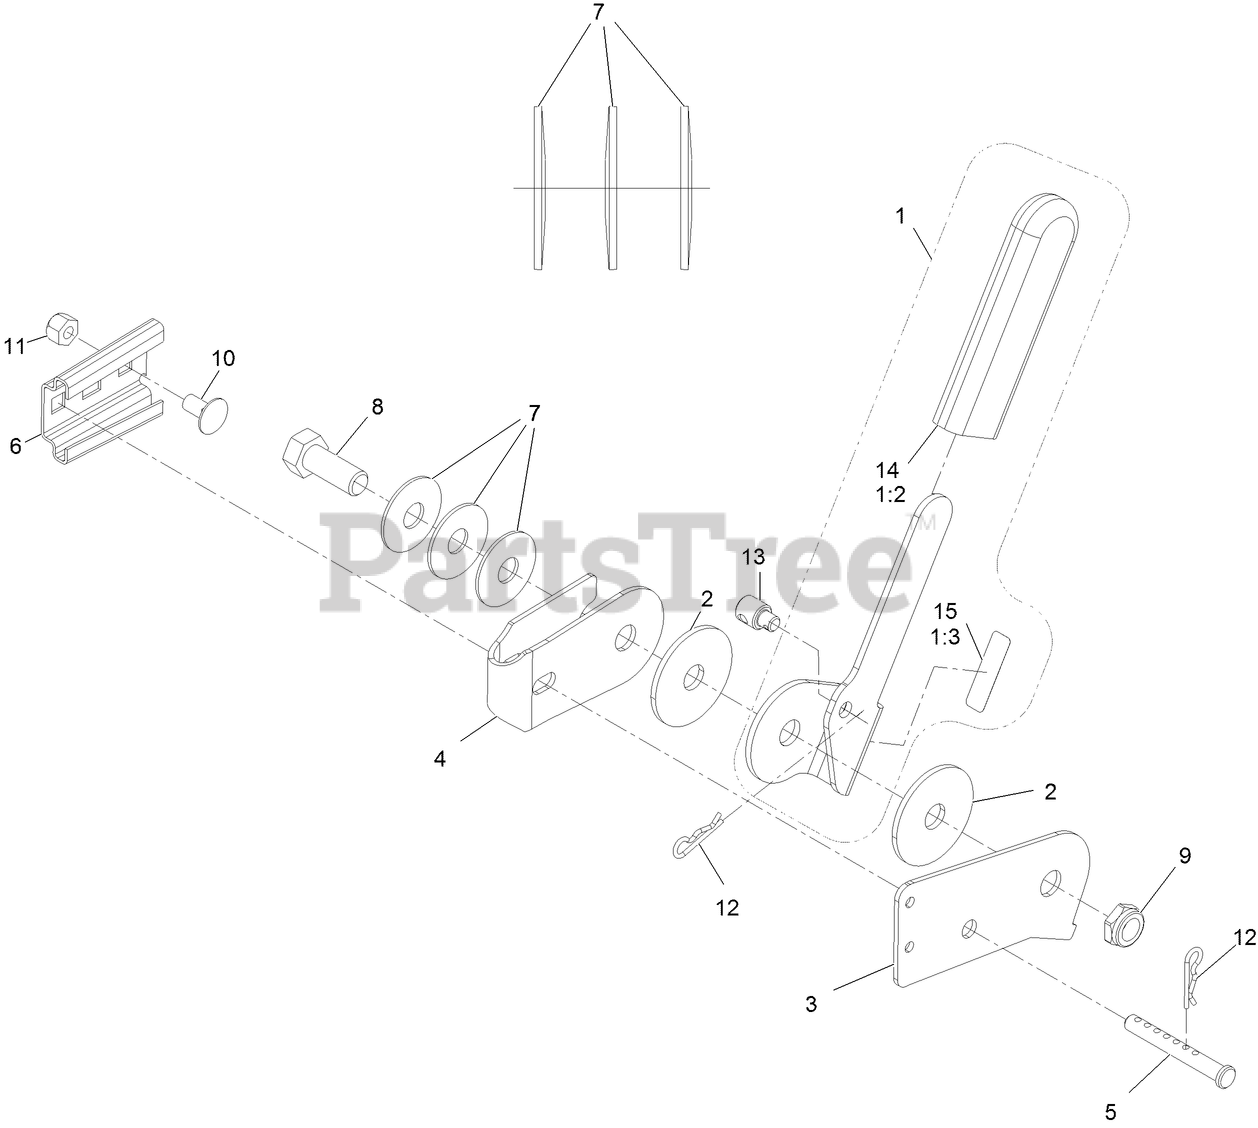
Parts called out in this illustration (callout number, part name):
1	CONTROL HANDLE ASM-OCD
1:2	GRIP-LEVER
1:3	DECAL-OPERATION
2	DISC-FRICTION
3	BRACKET,CONTROL MOUNT
4	BRACKET,HANDLE MOUNT
5	PIN-CLEVIS
6	BRACKET-MOUNTING,SMV
7	WASHER-DISC, SPRING
8	SCREW-HH
9	NUT-HEX
10	SCREW-CARR
11	NUT-LOCK, NI
12	PIN-COTTER
13	PIVOT, CONTROL CABLE
14	GRIP-LEVER
15	DECAL-OPERATION
